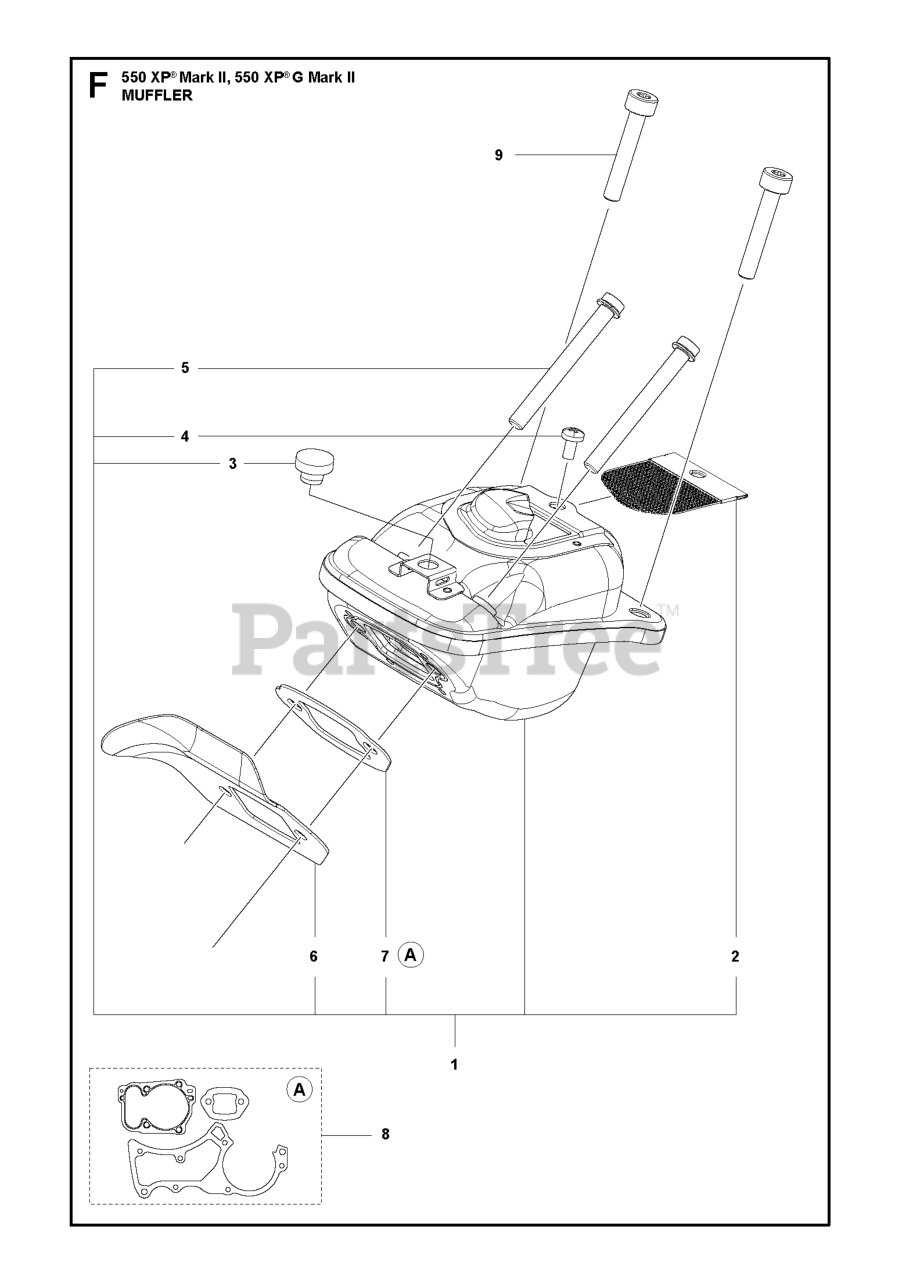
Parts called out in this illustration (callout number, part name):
1	MUFFLER KIT MUFFLER KIT
2	SPARK ARRESTER
3	RUBBER BUMPER
5	SCREW ITXSCM HEXABOULAR SOCKET
6	HEAT DEFLECTOR
7	MUFFLER GASKET
8	GASKET KIT MARK II
